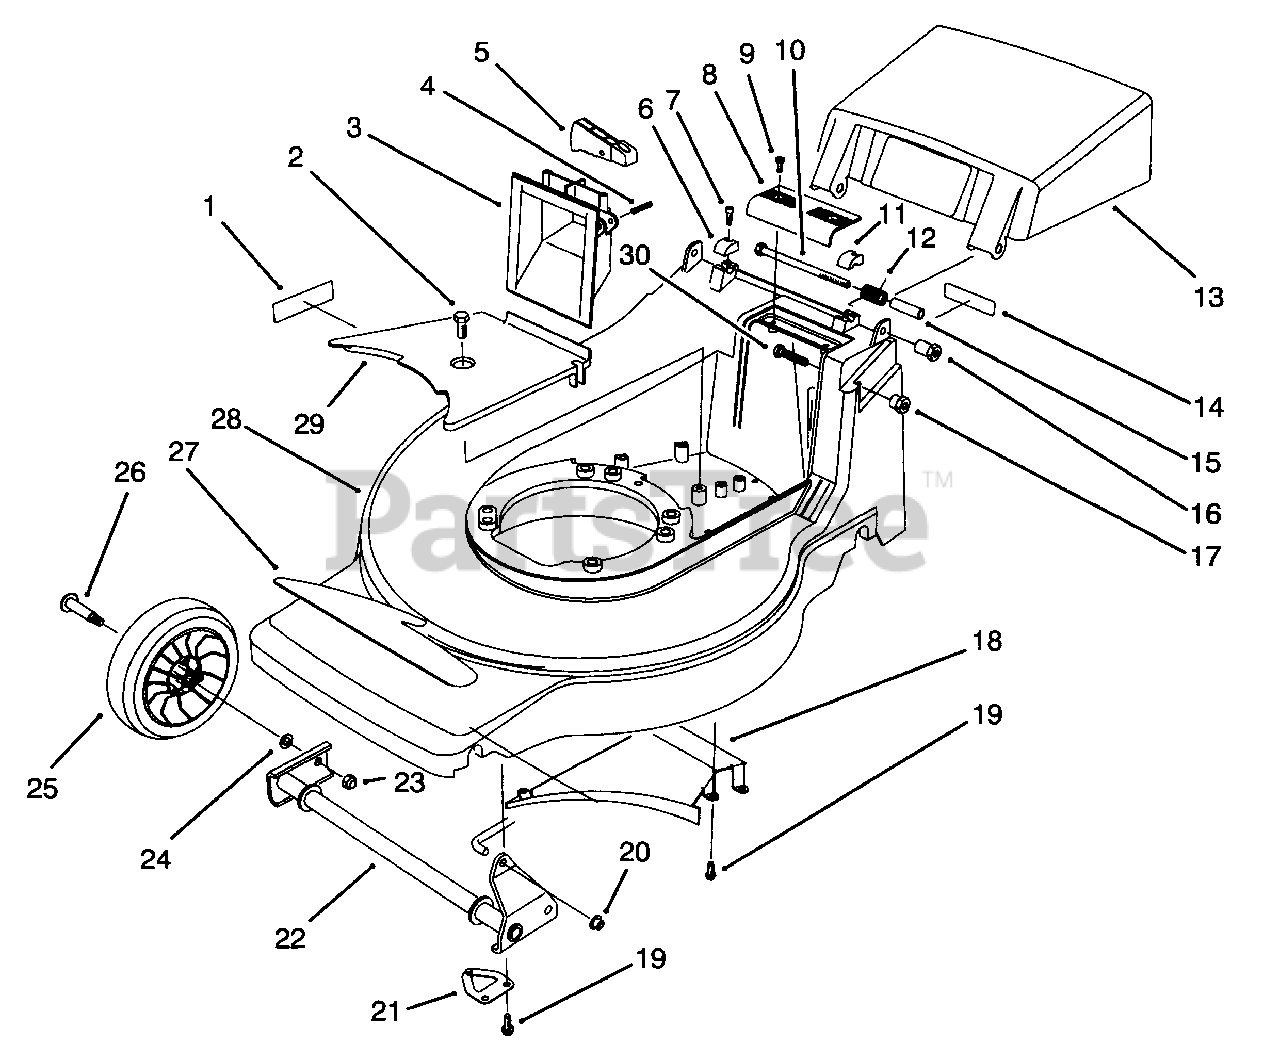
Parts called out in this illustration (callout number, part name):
1	Decal-DIN
2	Screw-Tapping
3	Grip-Lower
4	Pin-Groove
5	Trigger-HOC
6	Cap-R.H. Hinge Bolt
7	Screw-Thread Forming
8	Grip-Upper
9	Screw-Pan Hd. Phillips
10	Screw-Hex Hd. Cap
11	Cap-L.H. Hinge Bolt
12	Spring-Door
13	Door-Discharge
14	Decal-French Regulation
15	Spacer-Door
16	Spacer-Handle
17	Spacer-Handle
18	Ramp-Discharge
19	Screw-Tapping
20	Nut-Push
21	Retainer-Shaft
22	Pivot-Front
23	Nut-Lock
25	Wheel & Tire Assembly
26	Bolt-Wheel
27	Decal-Deck 400XP
28	Housing (Incl. Ref. #1)
29	Cover-Belt
30	Screw-Hex Hd. Cap
